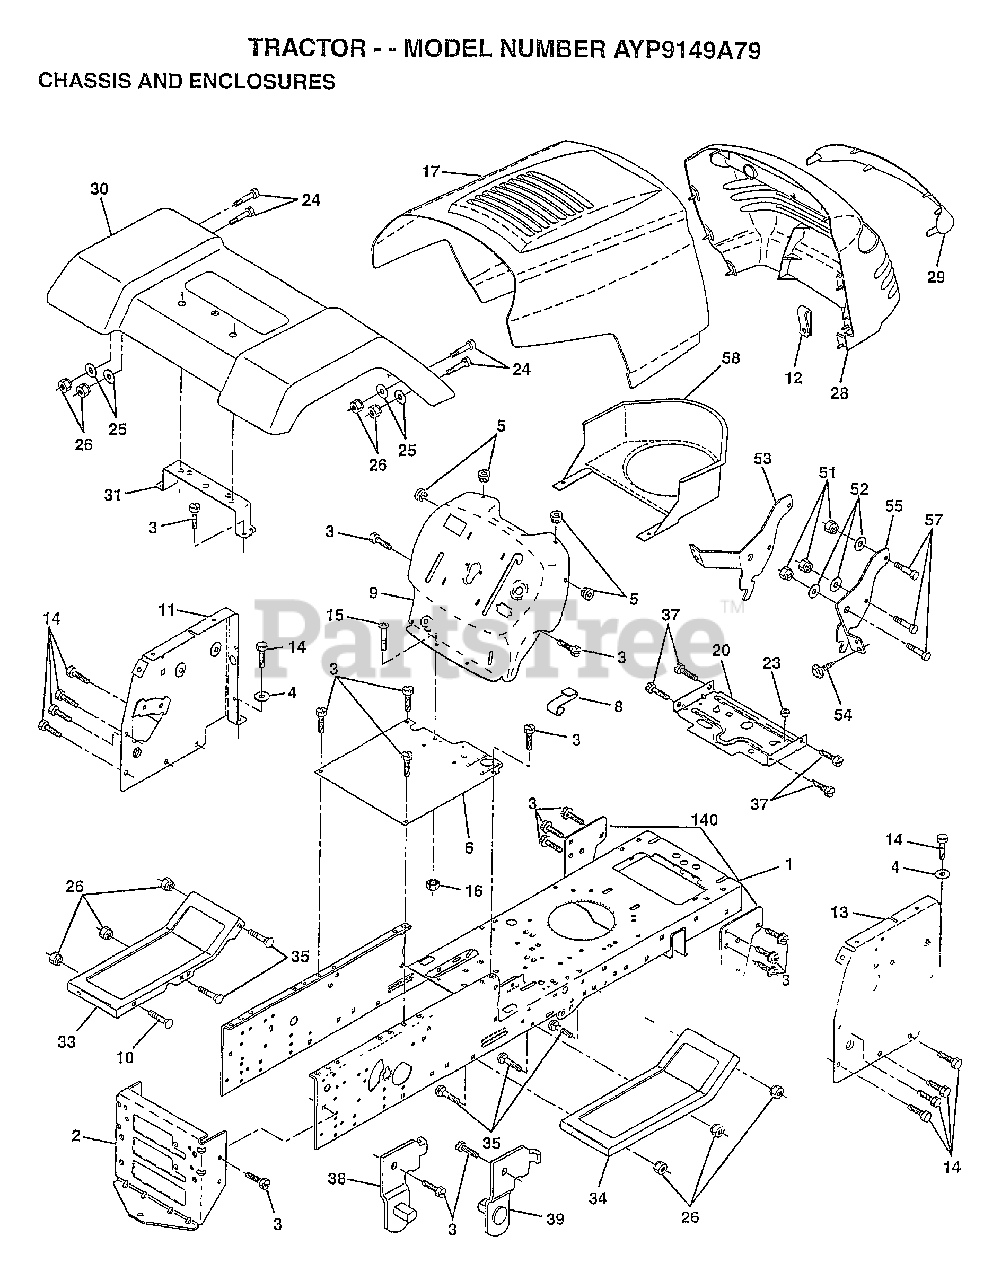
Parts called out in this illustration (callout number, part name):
1	CHASSIS ASM
3	SCREW
4	WASHER
5	BUMPER-HOOD/DASH
6	SADDLE
8	CLIP.RETAINER
9	DASH.SILKSCREENED
11	"PANEL-DASH,LH"
12	CLIP.TINNERMAN
14	SCREW LT
15	SCREW
20	"PLATE-MTG,BATT/FU"
24	BOLT
25	WASHER
26	NUT
28	GRILLE-MS428
29	LENS GRILLE
31	BRKT FENDER
33	FOOTREST LH
34	FOOTREST RH
35	BOLT
37	SCREW LT
38	BRACKET ASM LH
39	BRACKET ASM RH
51	NUT
52	WASHER
53	BRACKET.GRILLE.LH
55	BRACKET.GRILLE.RH
58	AIR DUCT
140	BRKT SUSPENSION
